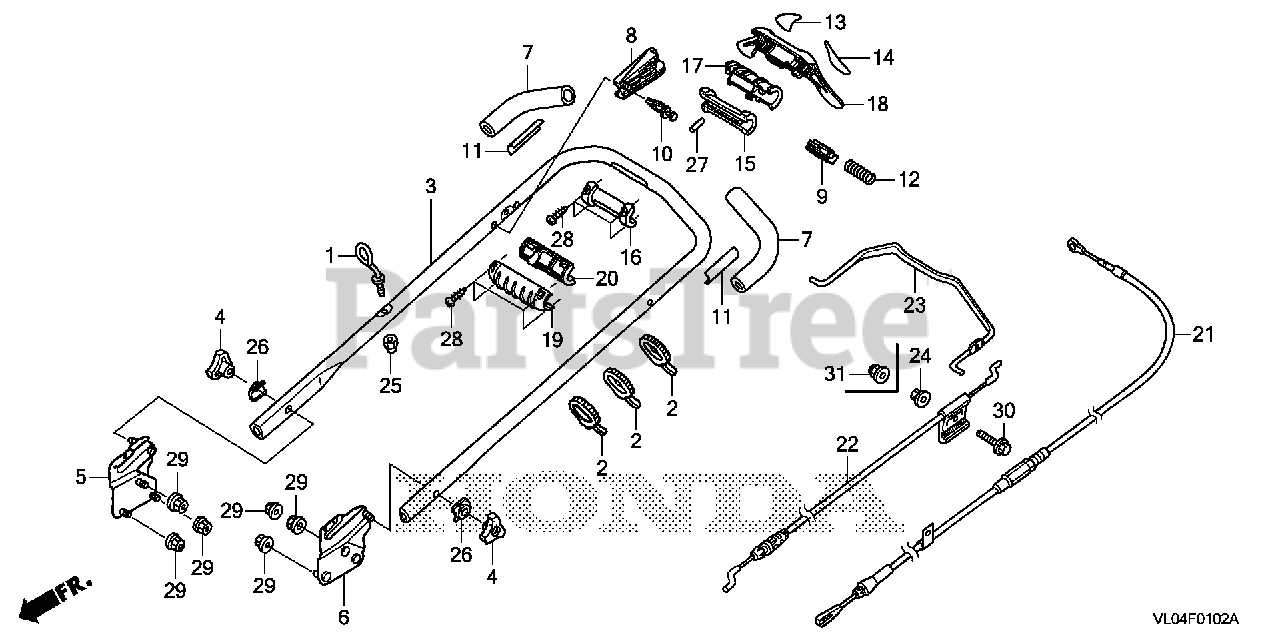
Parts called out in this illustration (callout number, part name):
1	GUIDE, ROPE
2	TIE, CABLE (157.5MM)
3	PIPE, HANDLE *NH105* (MAT BLACK)
4	GRIP, HANDLE JOINT
5	STAY, R. HANDLE
6	STAY, L. HANDLE
7	GRIP, HANDLE
8	STOPPER, LEVER
9	LEVER, SELECT
11	HOLD, GRIP
12	SPRING, SELECT LEVER
13	GRIP, R. PAD
14	GRIP, L. PAD
15	BRACKET, GRIP (UPPER)
16	BRACKET, GRIP (LOWER)
17	COVER, BRACKET (UPPER)
18	GRIP, CLUTCH (UPPER)
19	GRIP, CLUTCH (LOWER)
20	COVER, BRACKET (LOWER)
21	CABLE, CLUTCH
22	CABLE, BRAKE
23	LEVER, BRAKE *NH105* (MAT BLACK)
25	NUT, NYLON LOCK (6MM)
26	WASHER, FRAME JOINT
27	ROLLER (5X37)
28	SCREW, TAPPING (4X12)
29	NUT, FLANGE (8MM)
30	BOLT, FLANGE (6X45)
31	NUT, NYLON LOCK (6MM)
